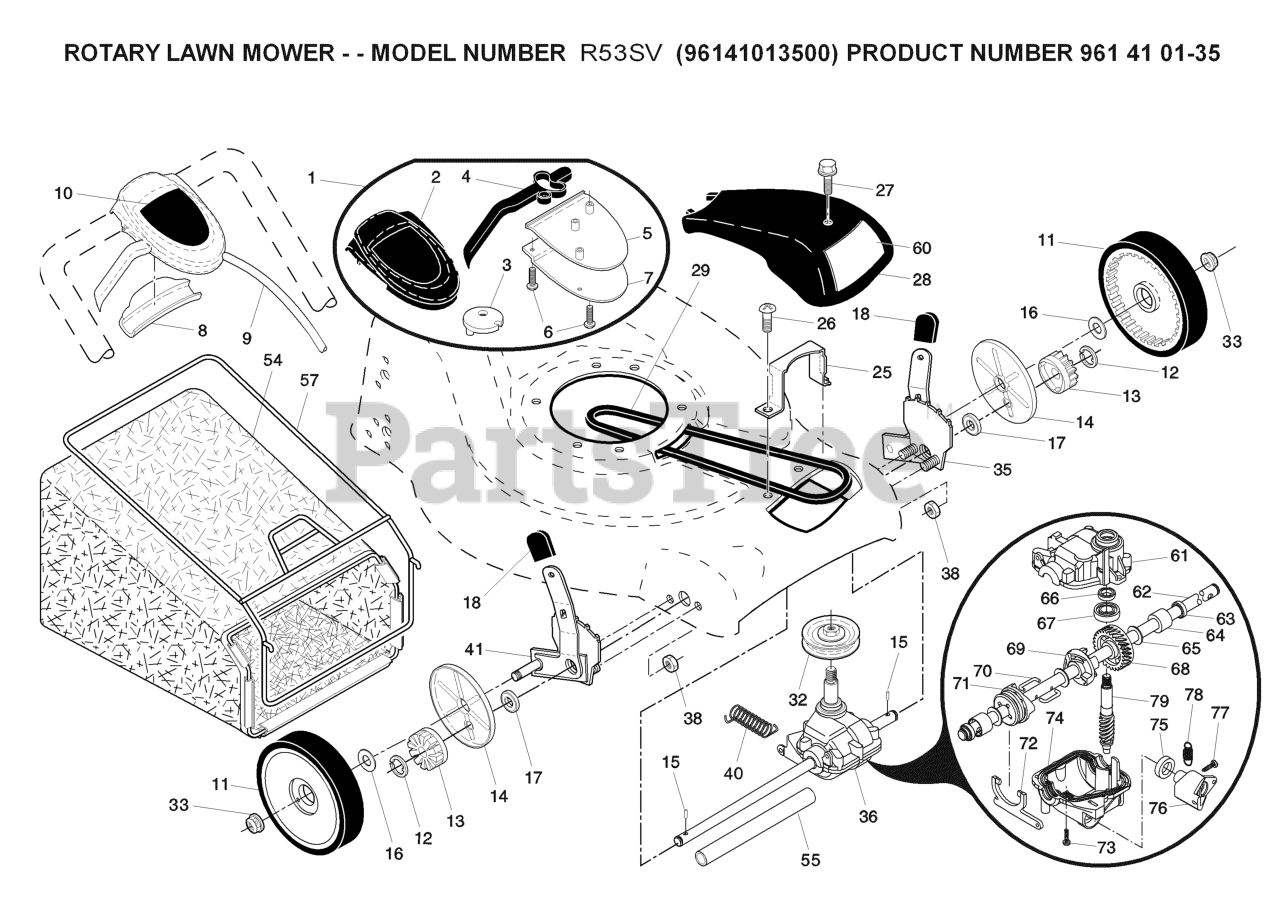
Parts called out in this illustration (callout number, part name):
1	CONTROL.DR.EZ.FWGD.SHORT.GY/BL
2	CASE.TOP.GRAY
3	PULLEY.CAM.DRIVE.CONTROL.HV
4	LEVER.SHORT.MARIGOLD.
5	CASE.BOTTOM.BLK
6	SCREW, PHILLIPS HEAD 10 X 5/8
7	BRACKET.DRIVE.CONTROL.MOUNT.BL
8	EZ WALK SNAP COVER PLATE
9	CABLE.ASM.
10	DECAL, DRIVE
11	WHEEL.8X1.75.MAG2.RAD3.GRY
12	E-RING 7/16 RE
13	PINION.14.TEETH.FGD
14	COVER.DUST.WHEEL
15	PAWL, DRIVE
16	WASHER FLUT
17	BEARING
18	SELECTOR KNOB
25	KEEPER.BELT.21.EZ.FWGD
26	SELF-TAPPING SCREW 5/16-18X3/4
27	SCREW, HEX HD TAPPING #10-24 1
28	COVER.DRIVE.21.FWGD.GRAY
29	BELT.DRIVE.FGD.
32	RP PULLEY.DRIVE.EZ
33	HEX FLANGE LOCKNT
35	RP KIT.ADJUSTER.ASM.
36	TRANSMISSION.21RD
38	LOCKNUT.NYLOC.1/4-20
40	SPRING RETURN
41	Kit, Wheel Adjuster, RH
54	Grassbag Assembly
55	DRIVESHAFT COVER
57	FRAME, GRASSBAG
60	DECAL DRIVE COVER
61	GEARCASE.HOUSING
62	SHAFT.OUTPUT
63	SEAL.OUTPUT.SHAFT
66	SEAL INPUT SHAFT
68	GEAR.27.TEETH.WALK.MOWER
70	WIRE, FORMED (15966)
74	GEARCASE.HOUSING.LOWER
77	SCREW.LEVER.
79	SHAFT INPUT (13041)
